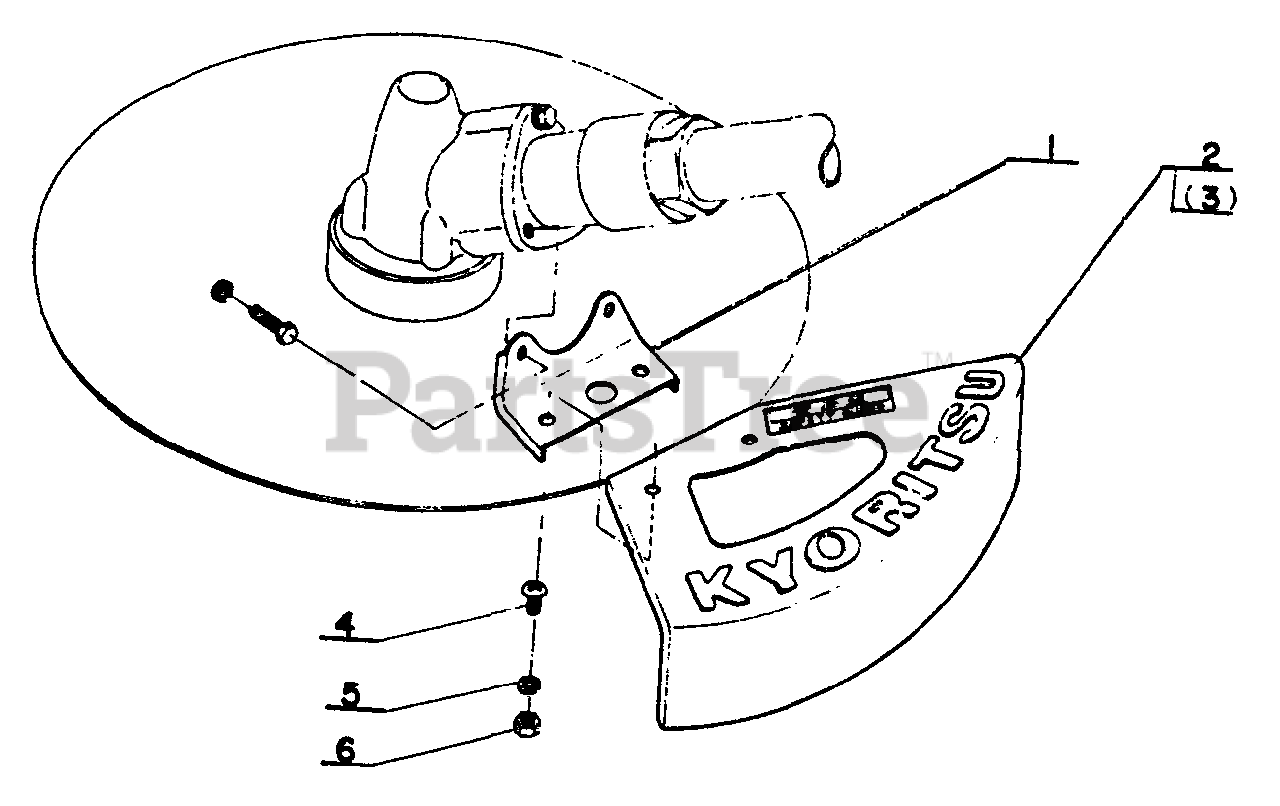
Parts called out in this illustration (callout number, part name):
1	SET PLATE, SAFETY GUARD
2	SAFETY GUARD
4	SCREW 5×8
5	WASHER, SPRING 5
6	NUT M5
